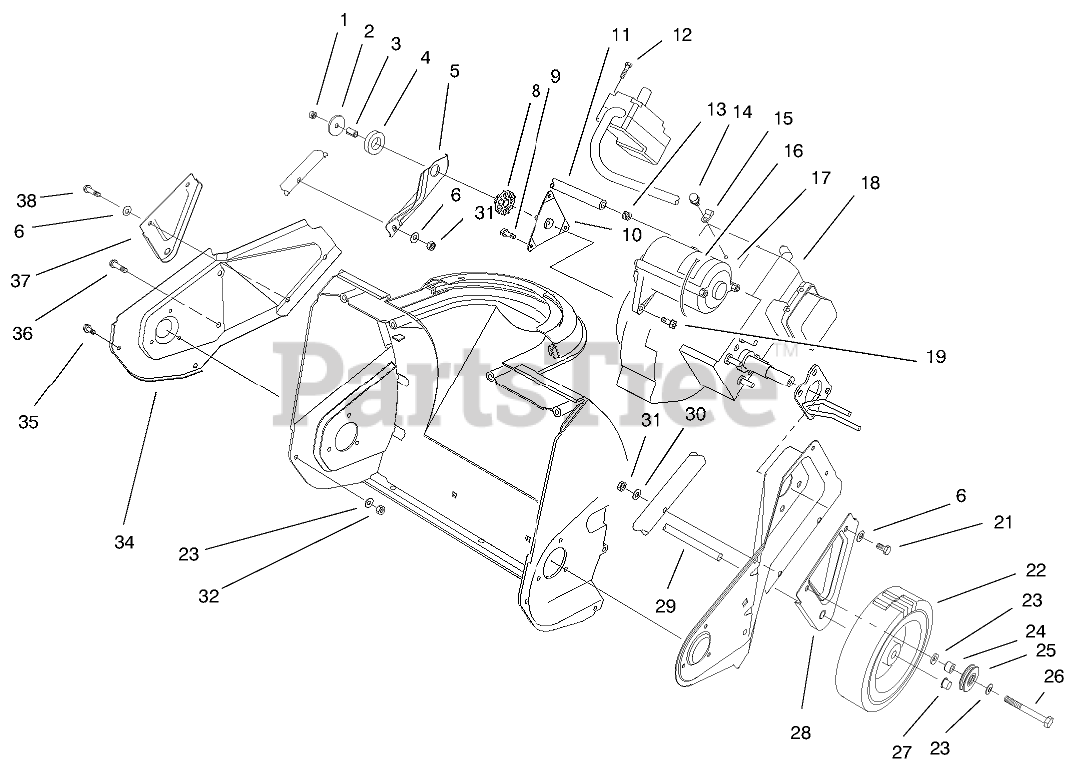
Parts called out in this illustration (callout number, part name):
1	NUT-LOCK, NI
2	WASHER-FLAT
3	SPACER-TUBULAR
4	RING-ISOLATOR
5	BRACKET-SUPPORT, ENGINE
6	WASHER-FLAT
8	BUSHING-ISOLATOR
9	WASHER-LOCK / EXT
9	SCREW
10	BRACKET AND STUD ASM
11	LINE-GAS
12	SCREW-PLASTITE
13	CLAMP-HOSE
15	CLAMP
16	TIE-CABLE
17	ASM-Switch Housing
17	Starter Motor ASM(Serv)(Model 38178)
19	SCREW-HH, TORX
21	SCREW-HH
22	WHEEL
23	WASHER-FLAT
24	SPACER-BLADE, ROTOR
25	CABLE-PULLEY
26	SCREW-HH
27	RETAINER-PUSH ON
28	Bracket-Wheel
30	WASHER
31	NUT-LOCK, NI
32	NUT-LOCK, NI
34	PLATE-SIDE, RH
36	SCREW-PLASTIC
37	BRACKET-WHEEL, RH
